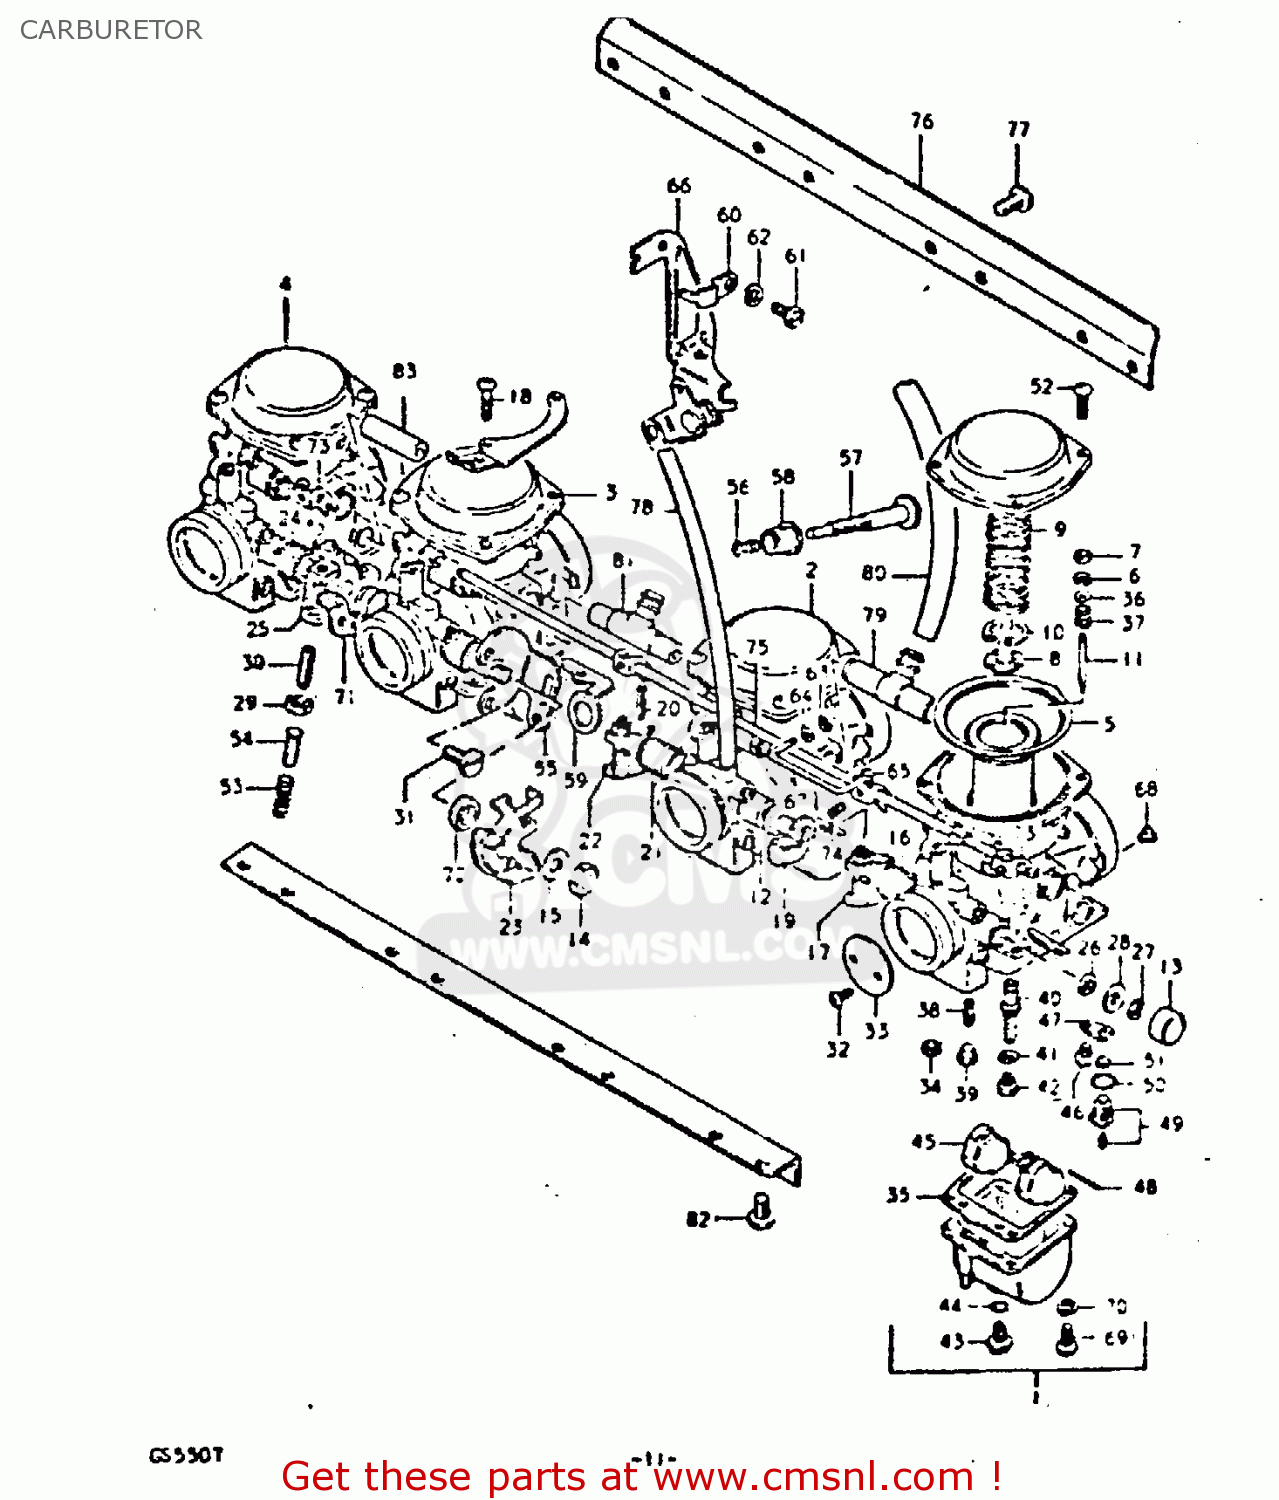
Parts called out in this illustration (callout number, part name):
1	CARBURETOR, NO.1
2	CARBURETOR, NO.2
3	CARBURETOR, NO.3
4	CARBURETOR, NO.4
5	DIAPHRAGM ASSEMBLY
6	CLIP,NEEDLE
7	RING
8	HOLDER,GUIDE
9	SPRING
10	E RING
11	NEEDLE, JET (5F42-3)
12	GASKET,THROTTLE SHAFT (NAS)
13	CAP
14	NUT
15	SCREW
16	SPRING,THROTTLE SHAFT
17	SHAFT,THROTTLE
18	SCREW
19	SHAFT,THROTTLE
20	PIN,THROTTLE SHAFT
21	SPRING,THROTTLE SHAFT
22	LEVER,THROTTLE SHAFT
23	LEVER ASSEMBLY,THROTTLE
24	SPRING,THROTTLE SHAFT
25	SHAFT,THROTTLE
26	SEAL
27	E RING
28	GASKET,THROTTLE SHAFT (NAS)
29	NUT
30	SCREW
31	SCREW,THROTTLE ADJUST B
32	SCREW
33	VALVE,THROTTLE (BUTTERFLY)
34	GASKET (NAS)
35	GASKET,FLOAT CHAMBER (NAS)
36	WASHER
37	SPRING
38	JET
39	PLUG,NEEDLE JET
40	JET, NEEDLE (X-6)
41	WASHER,NEEDLE NOZZLE
42	JET
43	PLUG,DRAIN
44	GASKET (NAS)
45	FLOAT
46	SCREW
47	PLATE
48	PIN,FLOAT
49	VALVE ASSEMBLY,NEEDLE
50	O-RING,NEEDLE VALVE
51	FILTER
52	SCREW
53	SPRING,THROTTLE SCREW
54	PIN,THROTTLE LEVER
55	BRACKET,THROTTLE ADJUST
56	SPRING
57	SCREW
58	BUSH
59	BRACKET,THROTTLE ADJUST
60	BRACKET,STARTER
61	BOLT
62	LOCK WASHER
63	CAP,LEVER
64	SEAT,SPRING
65	LEVER ASSY
66	BRACKET
67	ROD,STARTER LEVER
68	JET,AIR
69	SCREW
70	LOCK WASHER
71	SHAFT ASSEMBLY
72	WASHER
73	LEVER
74	SCREW
75	SHAFT,STARTER
76	BRACKET
77	SCREW
78	HOSE
79	NIPPLE
80	HOSE
81	NIPPLE,CARBURETOR
82	SCREW 6X12
83	NIPPLE
